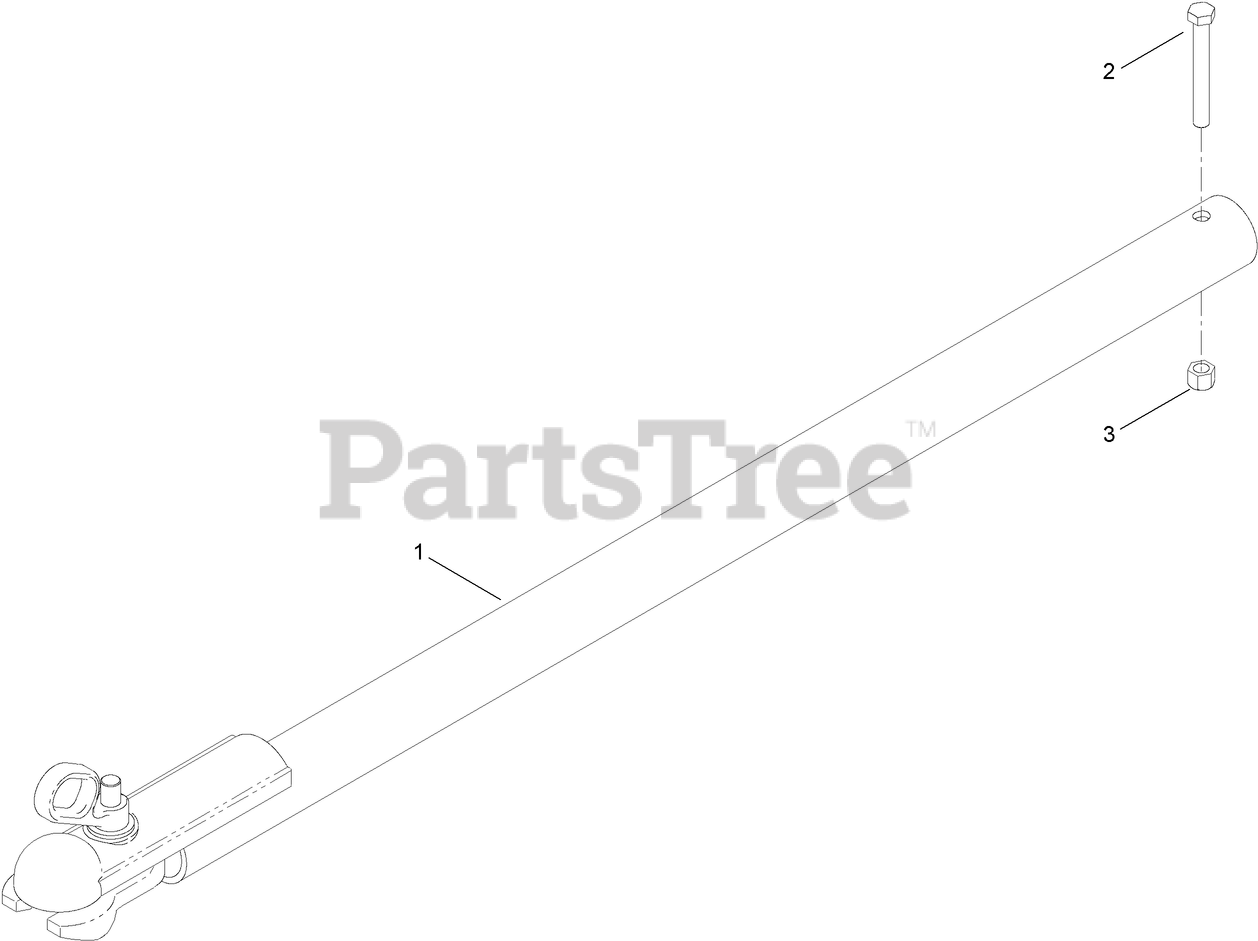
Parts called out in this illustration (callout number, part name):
1	HITCH-BALL, TOW POLE (FORGED 50IN)
2	SCREW-HH
3	NUT-LOCK, NI
